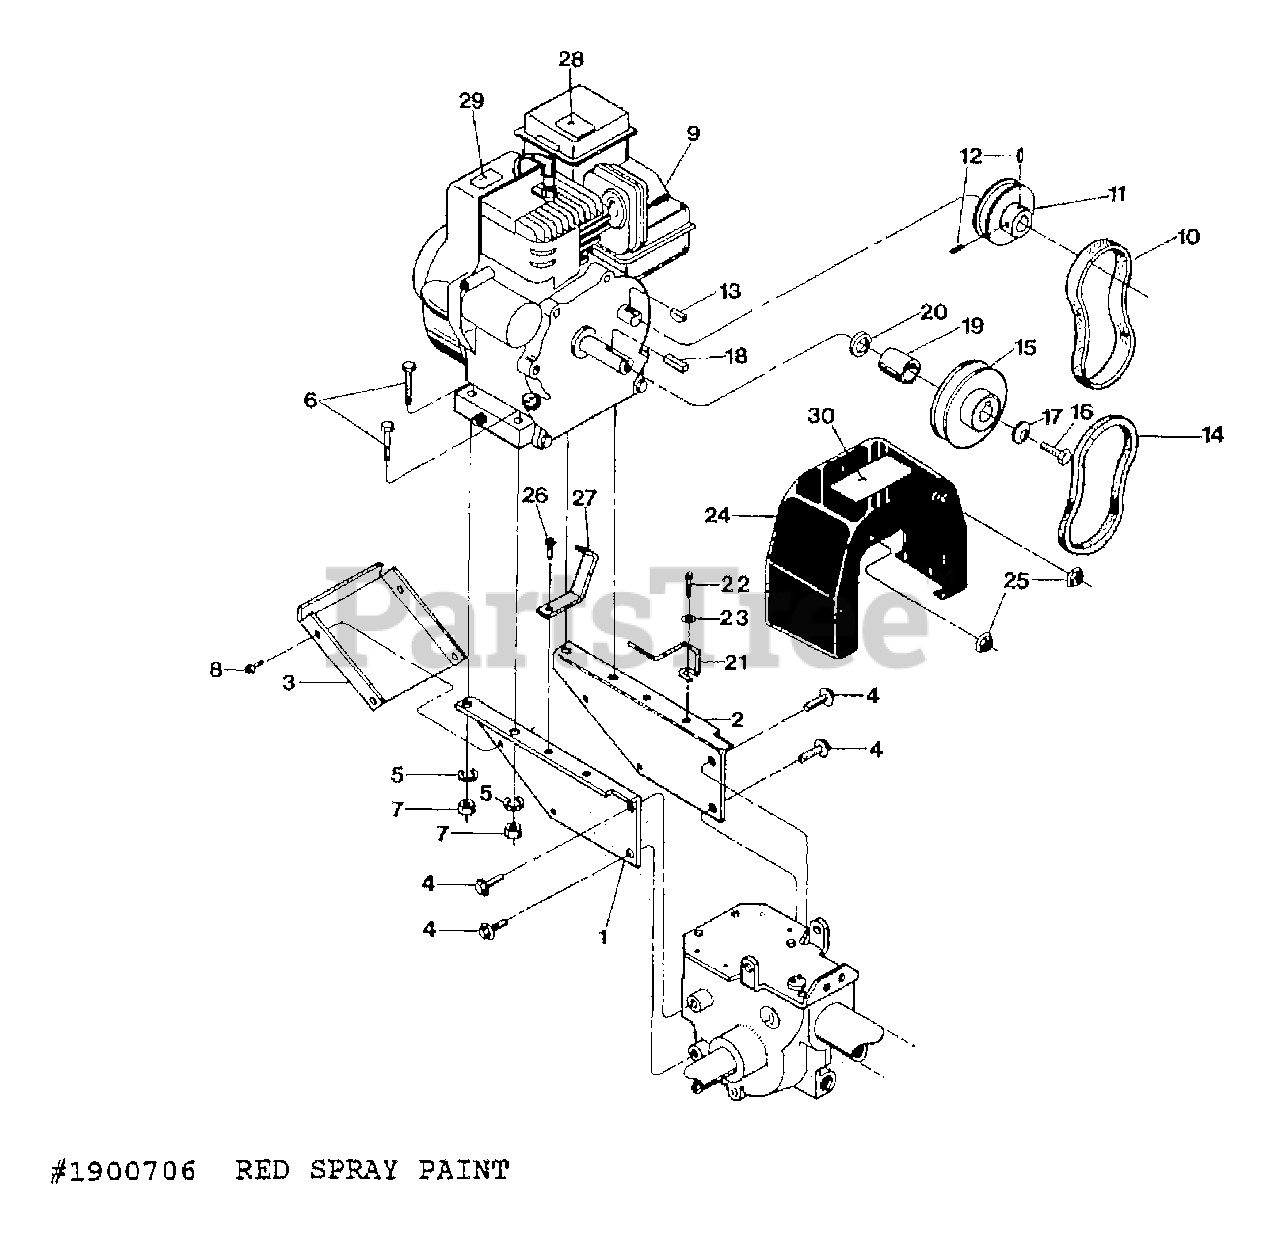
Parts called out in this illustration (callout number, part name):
1	BRKT-ENG LT P4
2	BRKT-ENG RT PNT
3	PAN-ENG BRKT PNT
4	SCR-HFLK 5/16-18X.75 ZP
5	WASHER-LK .312 ZP
6	SCR-HH 5/16-18X1.5 G5 ZP
7	NUT-HEX 5/16-18 ZP
8	SCR-HH SEMS 10-32 X .5 ZP
9	ENGINE, BRIGGS & STRATTON 5HP,
10	BELT-FLAT (SEE BELT SET BELOW)
11	PULLEY-REV DRILL/TAP
12	SCR-SS 1/4-20 X .25 (SECURES REVERSE ENGINE PULLEY)
13	KEY-WOODRUFF #5
14	BELT-V GROOVE FWD SMFRAME (SEE BELT SET BELOW)
15	PULLEY-ENGINE MACH
16	SCR-HH 5/16-24X.75 G5 ZP
17	WASHER-.827X.331X.098
18	KEY-.188 SQX1.0
19	SPACER-.938X.755X1.19
20	SHIM-1.0X.7656X.031
21	GUIDE-BELT FWD
22	SCR-HWH 1/4-20 X .75 STH
23	WASHER-FLAT 1/4 SAE
24	COVER-BELT W/DECAL (INCL. 30)
25	NUT-HFLK 5/16-18 ZP
26	SCR-HWH 1/4-20 X .5 STH
27	GUIDE-BELT REV PNT
28	DECAL - HOT SURFACE
29	DECAL-STABIL STARTING
30	DECAL-BELT COVER OPC
